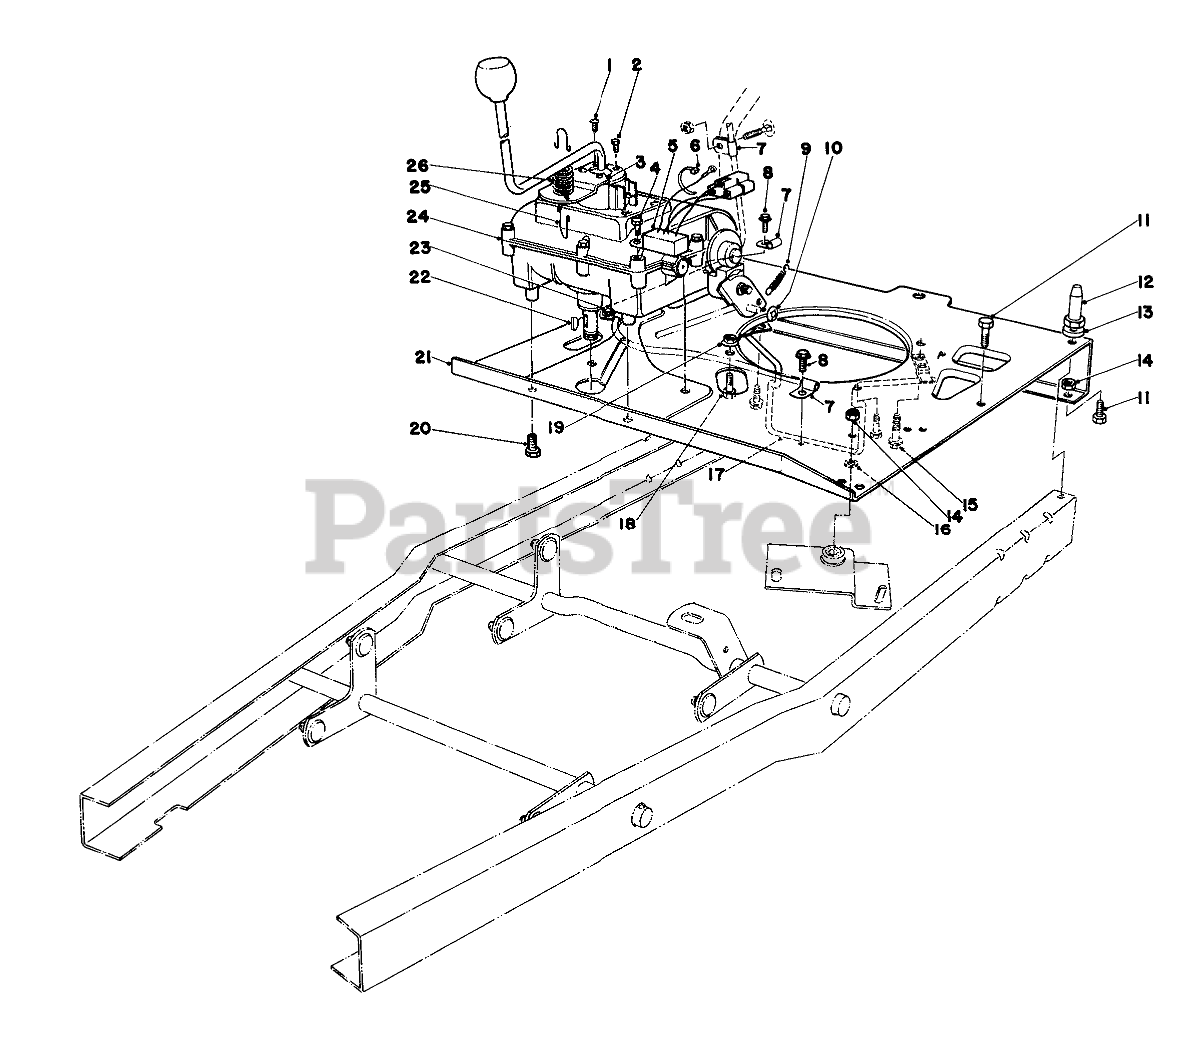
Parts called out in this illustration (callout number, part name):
3	Neutral Bracket
5	INTERLOCK MODULE
6	TIE-CABLE
7	CLIP-FUEL LINE
8	SCREW
9	SPRING-RETURN, BRAKE
10	PUSH ON SPEED NUT 1/4
11	SCREW-HH
12	PIN-MOUNTING, LOWER
13	SPACER-PIN, MOUNTING
14	NUT-LOCK, CONE
15	SCREW-HWHTF
16	WASHER-PLAIN
17	Belt Guide
18	SCREW-HH
19	NUT-HF
20	5/16-18 X 5/8 SEMS SC
21	Plate-Engine
22	KEY-WOODRUFF
23	SCREW-HHFTF
24	Transmission
25	Neutral Spring Wire
26	SPRING
